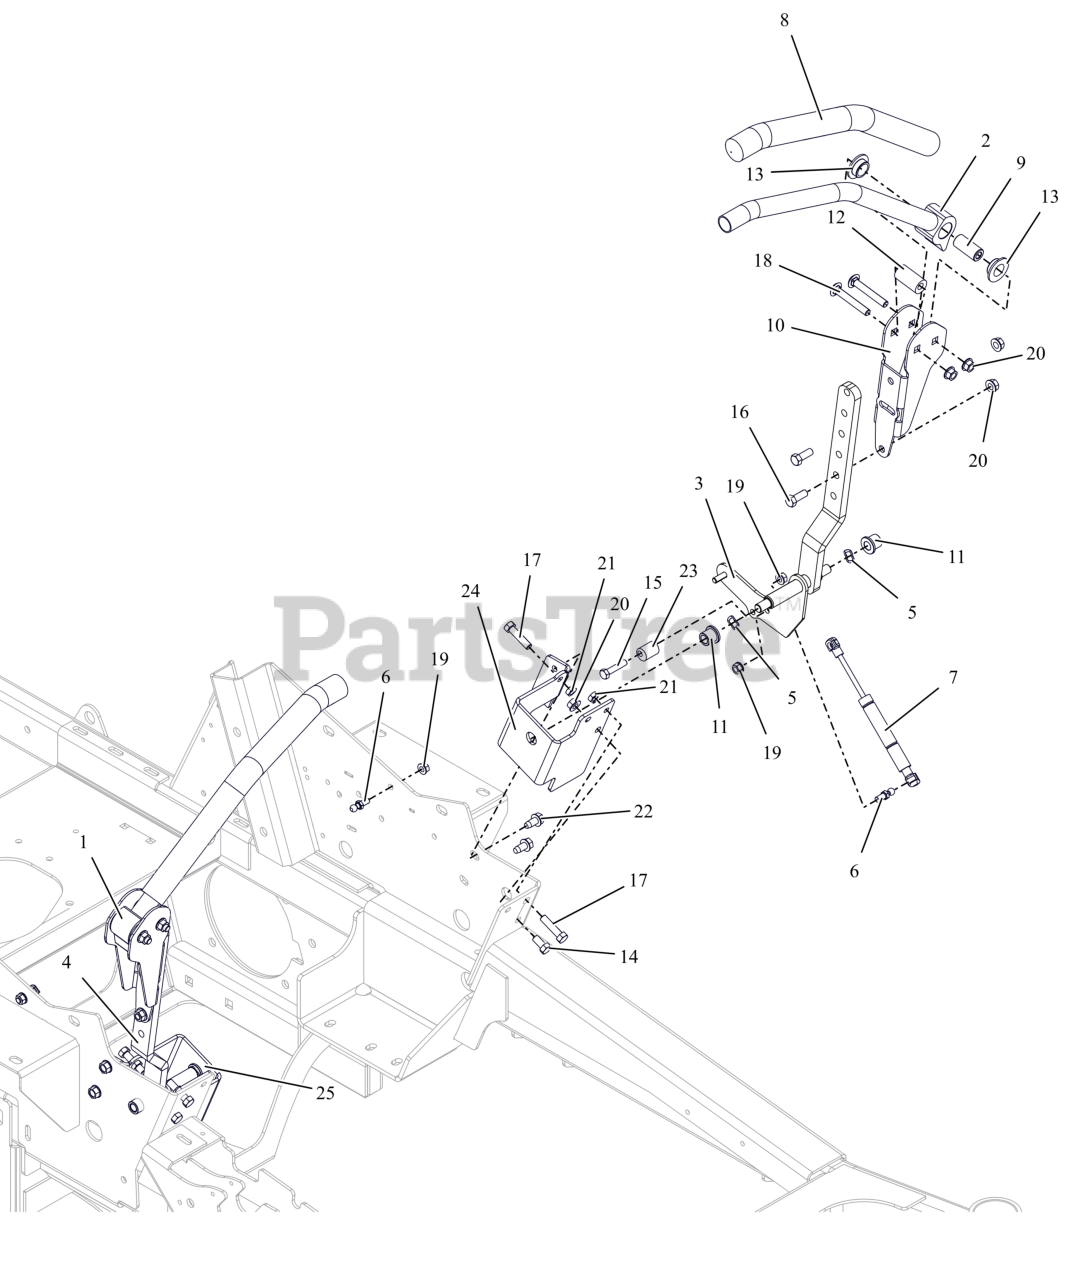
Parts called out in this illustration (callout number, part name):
1	WLDMT, CONTROL HANDLE (RED)
2	WLDMT, CONTROL HANDLE (RED)
3	WLDMT, LH LOWER CONTROL ARM (RED)
4	WLDMT, RH LOWER CONTROL ARM (RED)
5	WAVE WASHER .531X.781X.125FH
6	STUD- BALL
7	DAMPER, CONTROL
8	GRIP, HANDLEBAR
9	SPACER, STEERING ARM
10	BRKT, ADJ UPPER CONTROL ARM (RED)
11	BHSG-FLG .500X.750X.750X.125
12	BSHG, ECCENTRIC.406X.875X1.625
13	BSHG, FLANGED .762 X 1.48 X .44 IGLIDER
14	BLT,HEX .38-16X.75 G5 ZCC
15	BLT, HEX .31-18X1.50 G5 ZCC
16	BLT,HEX .38-16X1.00 G5 ZCC
17	BLT, HEX 0.375-16X1.5FULL G5 ZCC
18	BLT, RHSSN.38-16X2.50 G5 ZCC
19	NUT,LK-CTR-FLG .31-18 GF ZCC
20	NUT-LK-CTR-FLG .375-16 GF ZCC
21	NUT-JAM .375-16 G2 ZCC
22	SCR,TAP .375-16X.75 HWH TR ZCC
23	ECCENTRIC
24	BRKT, CONTROL ARM - LEFT (RED)
25	BRKT, CONTROL ARM - RIGHT (RED)
